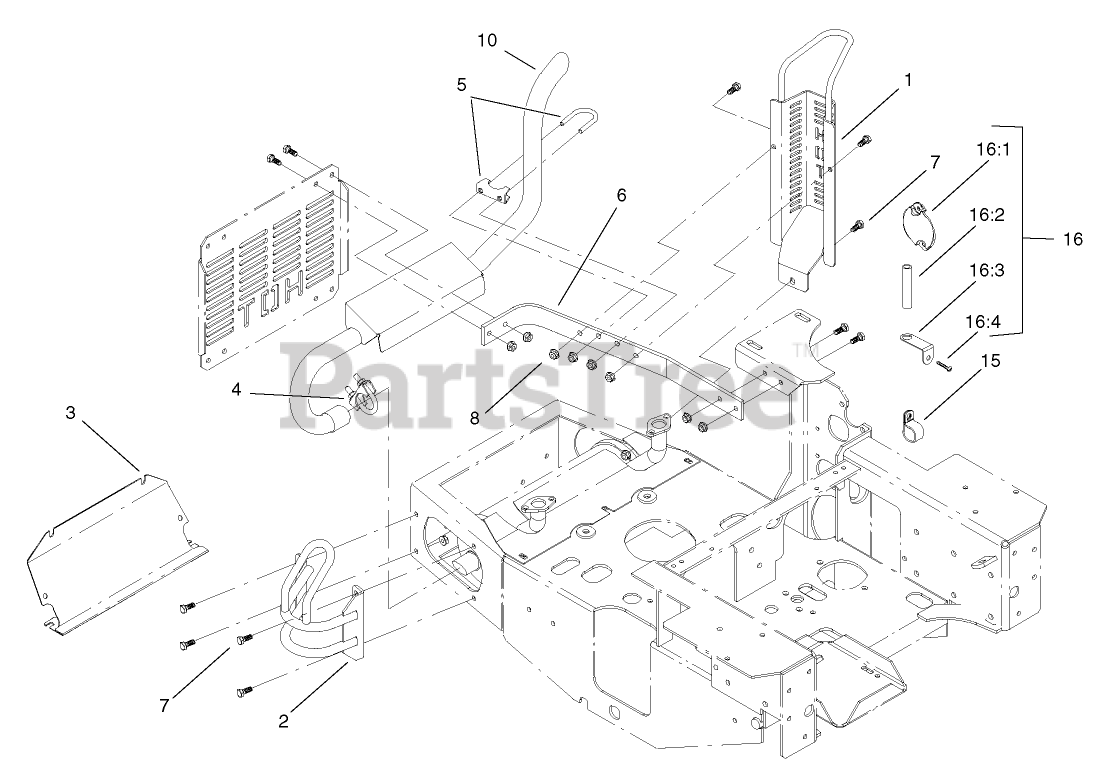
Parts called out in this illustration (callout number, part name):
1	LH Exhaust Guard ASM
2	RH Exhaust Guard ASM
3	Shield-Heat
6	Strap,Eng Guard LH Exhaust
7	SCREW-HH
8	NUT-HF
10	TAILPIPE
15	CLIP-LOOM
16	Shield-Heat, Fuel Pump
16:1	Shield-Heat, Fuel Pump
16:2	Tube-Vent
16:3	Bracket
